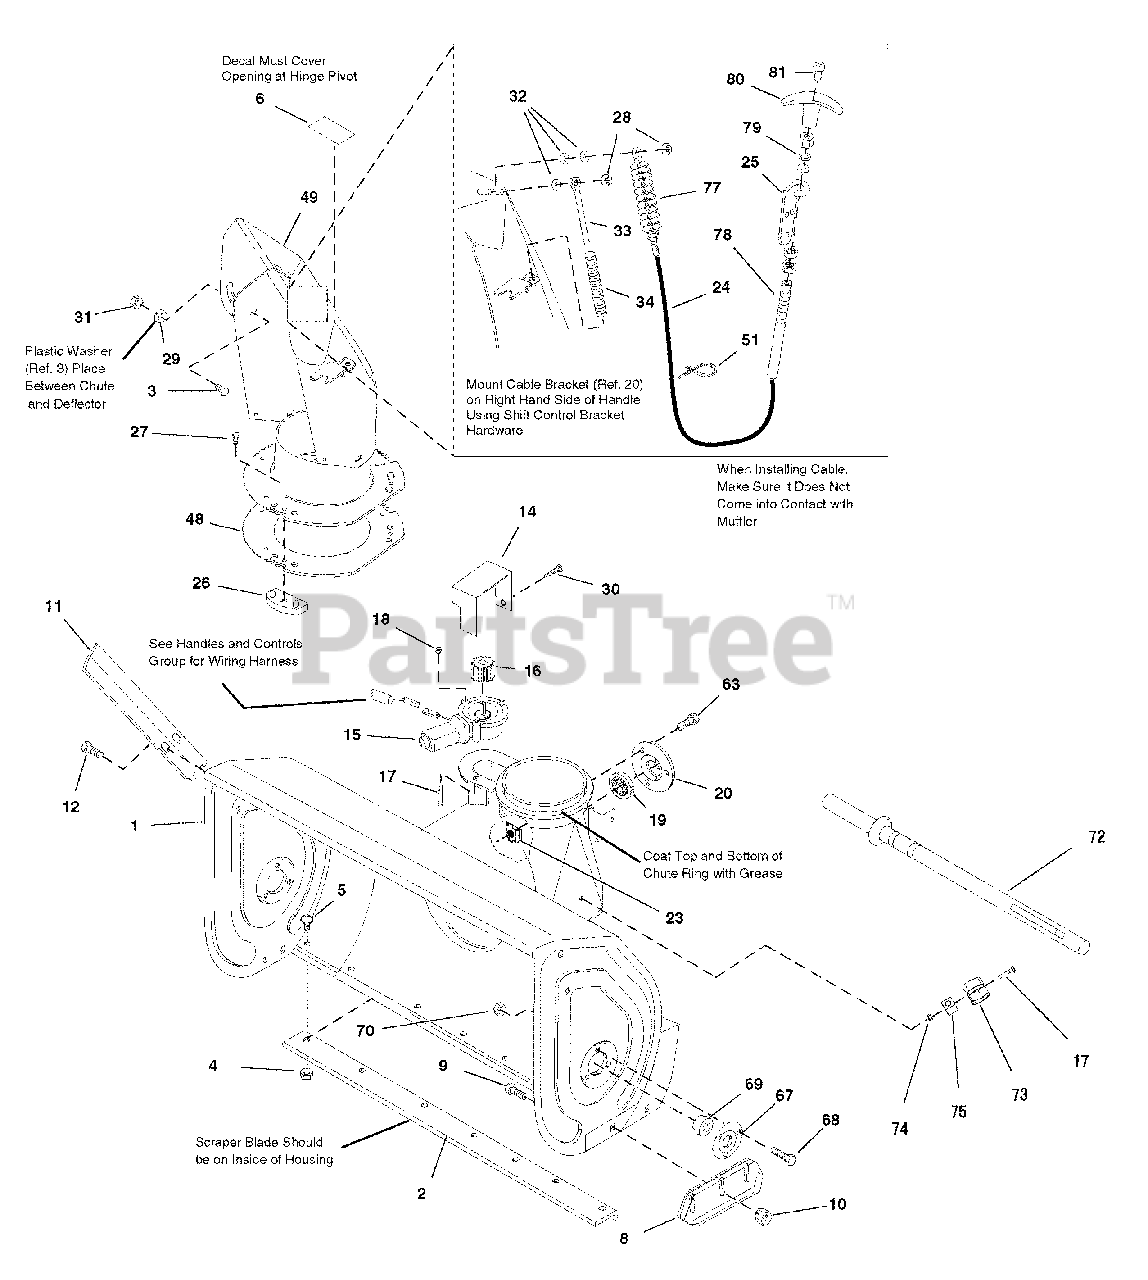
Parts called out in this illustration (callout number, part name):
1	HOUSING ASSEMBLY, 24"
1	HOUSING ASSEMBLY, 28"
1	HOUSING ASSEMBLY, 32"
1	HOUSING ASSEMBLY, 38"
2	BLADE, Scraper for 24"
2	BLADE, Scraper for 28"
2	BLADE, Scraper for 32"
2	BLADE, Scraper for 38"
3	CARRIAGE BOLT, 5/16-18 x 3/4, G5
4	NUT, Hex Flange, 5/16-18 Two-Way Lock
5	CARRIAGE BOLT, 5/16-18 x 5/8, G5
6	DECAL, Orange Strip Hinge Snow Chute
8	SKID SHOE
9	CARRIAGE BOLT, 3/8-16 x 3/4, G5
9	CARRIAGE BOLT, 3/8-16 x 1, G5
10	NUT, Hex Flange, 3/8-16 ESNA
11	CUTTER, Drift w/Tabs
12	SCREW, Hex Washer Head Taptite, 5/16-18 x 3/4
14	COVER, Gear, 38"
15	MOTOR, Spout Rotator, 38/42"
16	PINION, 1.417 OD .296 Slot 1-1/4 Long 16T Powdered Metal
17	SCREW, Hex Washer Head Slot, #10C x 1-1/4, G2
18	NUT, Hex Whiz Lock Flange, #10-24
19	BEARING, 3/4 ID x 1.78 OD x .61 Long Greased
20	BEARING RETAINER
23	RETAINER, Nut, 5/16-18 .057/.092
24	CABLE & KNOB ASSEMBLY
25	BRACKET, Chute Cable Snow, .179 Thick
26	HOLD DOWN, Chute, Nylon
27	SCREW, Hex Washer Head Taptite, 10-14 x 5/8
28	NUT, Push Pal, 1/4 Diameter Stud Capped
29	WASHER, Nylon, .388 x 1.12 x .03
30	SCREW, Hex Washer Head Taptite, 1/4-20 x 3/8
31	NUT, Hex Flange, 5/16-18 ESNA
32	SPACER, .265 ID x .37
33	ROD, 5/16 Diameter 5.88 Long
34	SPRING, Compression
48	GEAR, Chute, 10 OD 6.65 ID .105 Thick
49	CHUTE ASSEMBLY, with Pigtail Orange
51	TIE, Self Locking, .184 Wide 7.31 Long
63	SCREW, Hex Whiz Lock Flange, 5/16-18 x 3/4
67	FLANGE, Bearing, 1.937
68	CAPSCREW, Hex Head, 5/16-18 x 5/8, G5
69	BEARING, Ball
70	NUT, Hex Whiz Lock Flange, 5/16-18
72	STICK, Snow Cleanout w/Brush, Plastic
73	CLIP, Retainer
74	NUT, Hex Lock, 10-24 w/Nylon Insert
75	BLOCK, Universal Pivot
77	BOOT, Bellows
78	COLLET
79	SEAL, Rod
81	SCREW, 8-32
